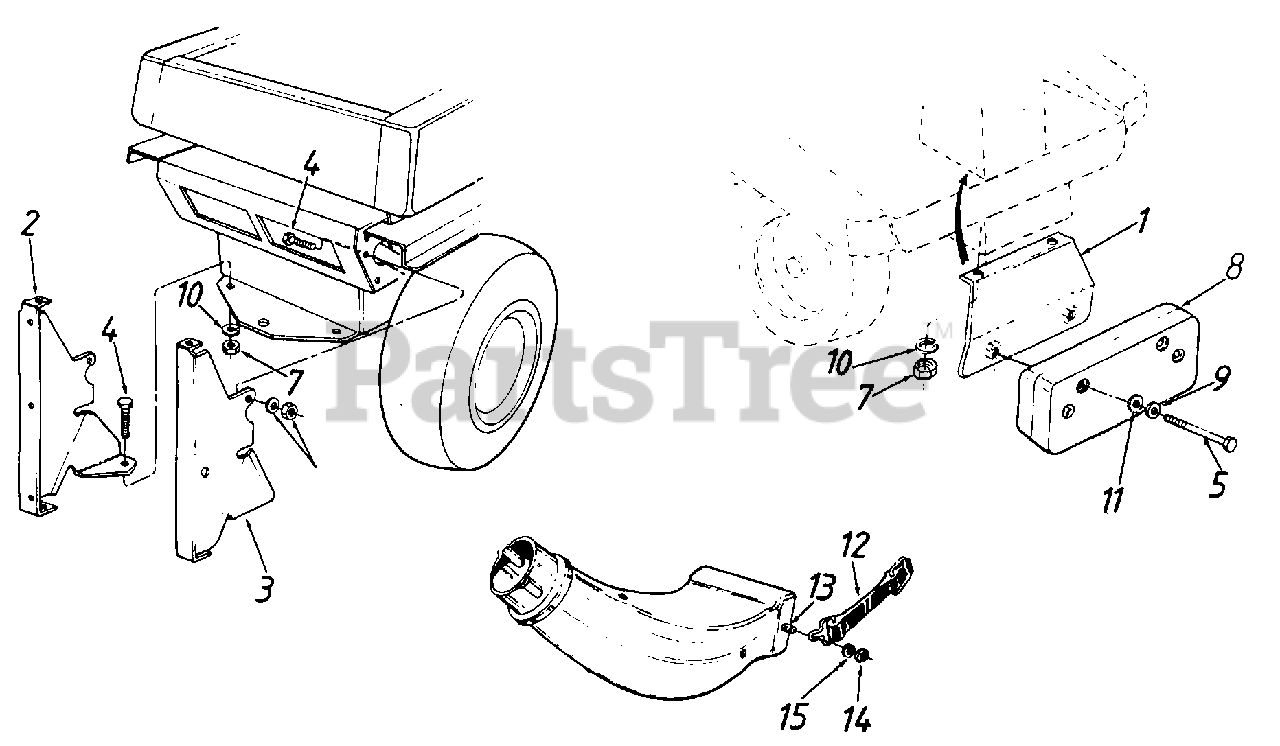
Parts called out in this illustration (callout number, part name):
1	BRACKET-SUPPORT
2	BRACKET-SUPPORT-RH
3	BRACKET-SUPPORT-LH
4	SCREW-HEX 5/16-18 X 1.00
5	SCREW-HEX 3/8 X 4.5 N.C GR. 5
7	NUT-HEX 5/16-18
8	COUNTERWEIGHT
9	WASHER-BELL .400 ID X .88 X .060
10	WASHER-LOCK-5/16
11	WASHER-FL
12	STRAP ASSY-RETAINER
13	SCREW-HEX 1/4-20 C .62
14	NUT-INS LOCK 1/4-20
15	WASHER-SPRING.270 ID X.51 OD X.030
